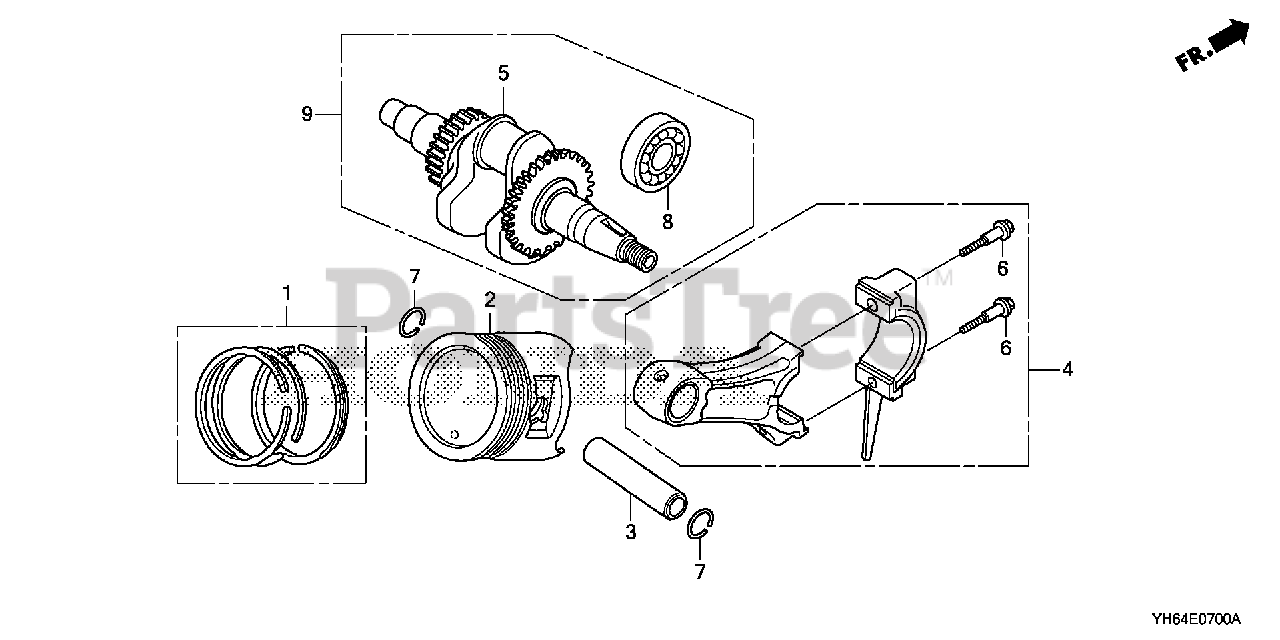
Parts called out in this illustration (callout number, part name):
1	RING SET, PISTON (STD) (RIKEN)
2	PISTON (STD)
3	PIN, PISTON
4	ROD ASSY., CONNECTING (UNDER SIZE)
4	ROD ASSY., CONNECTING
5	CRANKSHAFT
6	BOLT, CONNECTING ROD (6X34.5)
7	CLIP, PISTON PIN (18MM)
